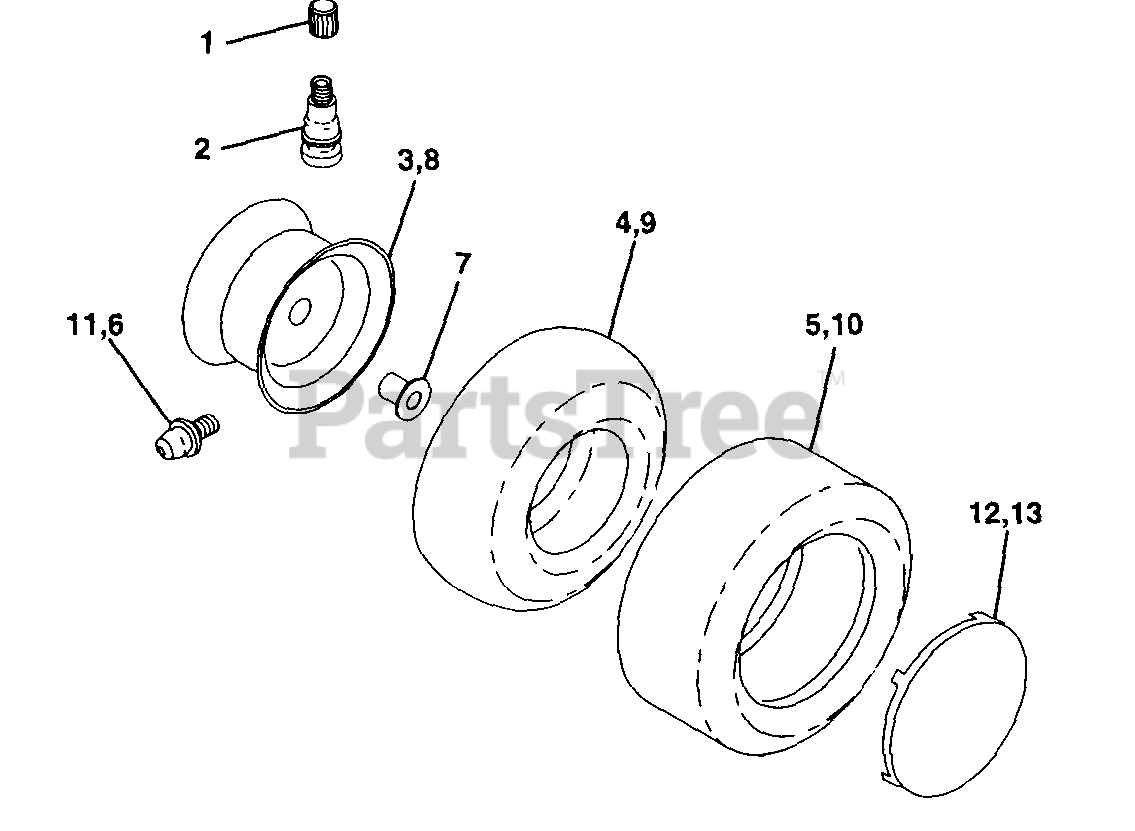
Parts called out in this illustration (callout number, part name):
2	VALVE STEM LT
3	RIM ASSY-FRONT
4	TUBE.16X6.5/7.5-8
5	TIRE HEAVY DUTY
6	FITTING LT.
7	BEARING T
8	RIM.ASM.12X7.REAR.WHITE
9	TUBE.23X9.5-12
10	TIRE HEAVY DUTY
11	ZERK FITTING M
12	CAP,HUB REAR
13	COVER,WHEEL
